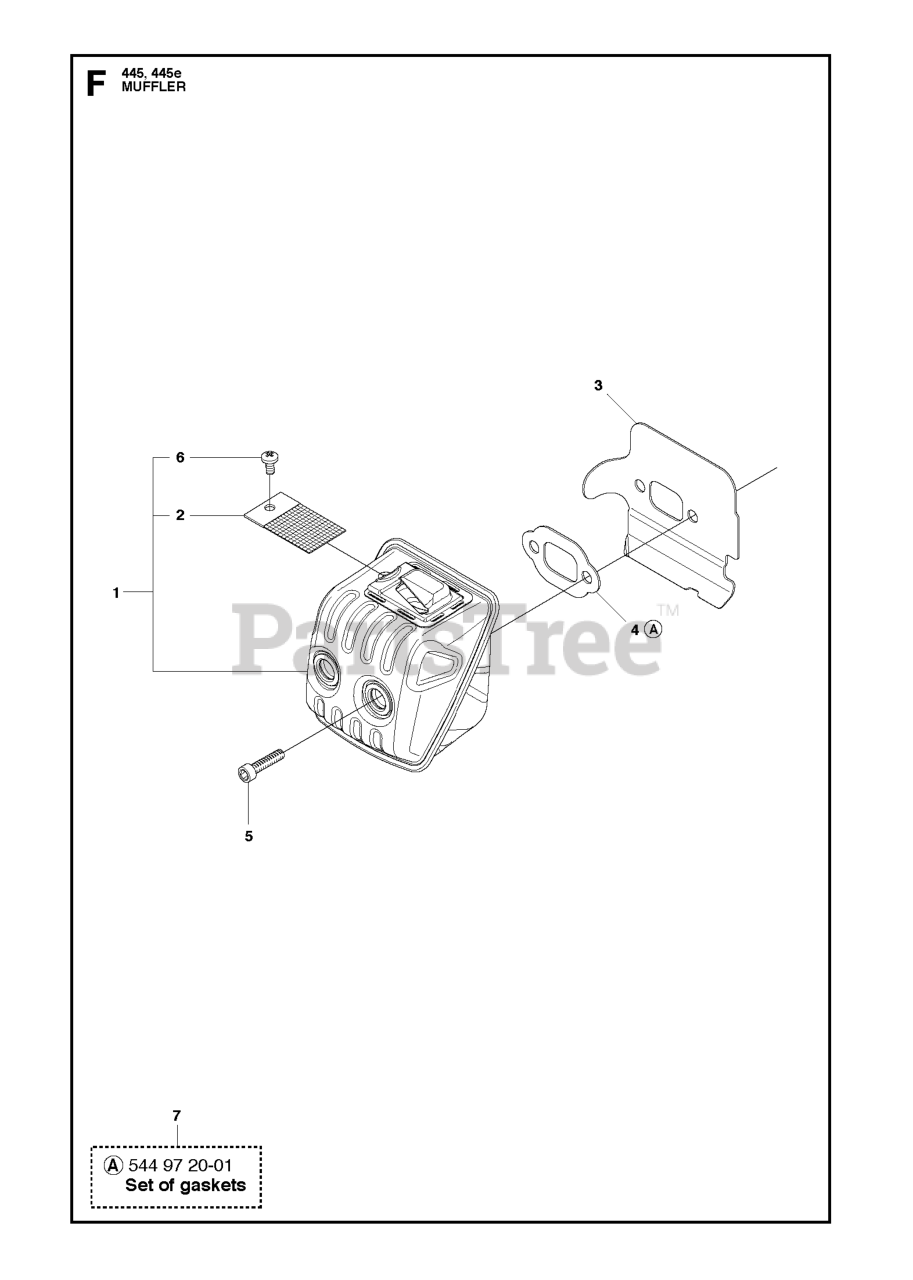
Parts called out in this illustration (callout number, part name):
1	MUFFLER ASSY
2	SPARK ARRESTER
2	SCREEN
3	HEAT DEFLECTOR
5	SCREW MC6S 6X16
6	SCREW
7	GASKET KIT
